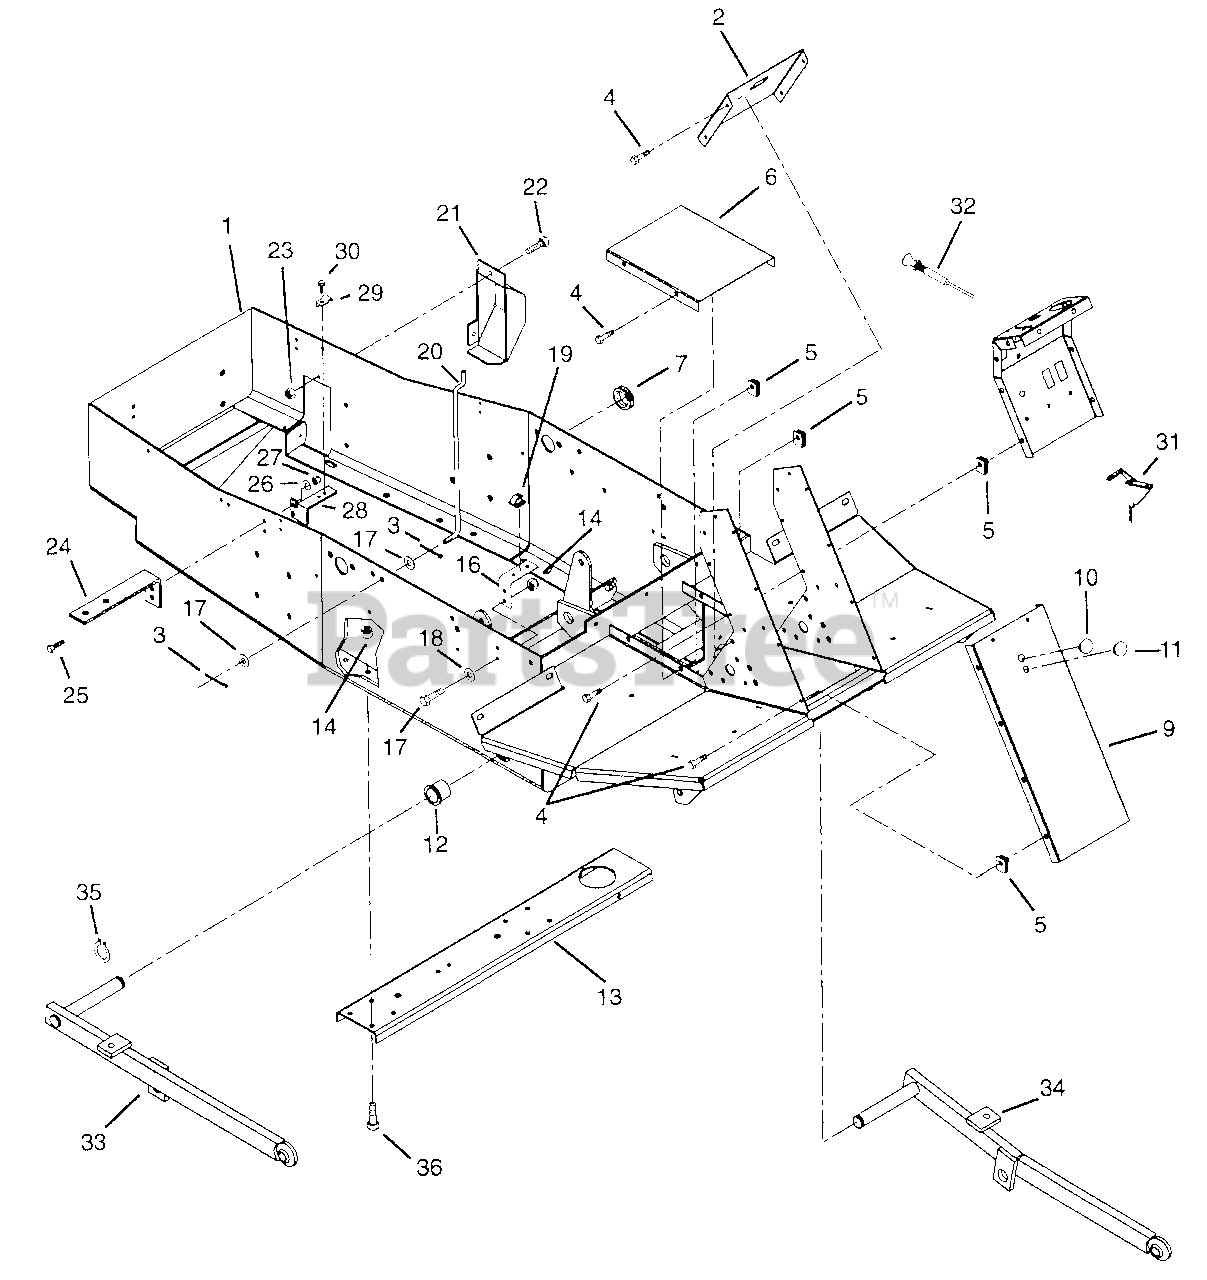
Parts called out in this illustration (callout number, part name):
1	Weldment, PM-350 Frame
2	Panel, Brake Lock
3	Pin-Cotter .09 x .75
4	Screw-Machine .25-20
5	Nut-Retainer .25-20 x .56
6	Panel, Access
7	Grommet, 1.25
8	Panel, Instrument
9	Panel, Front
10	Hole Plug
11	Plug, Hole
12	Bushing, Flange Nylon 1.25 x 1.50 x 1.50
13	Grommet, 1.25
14	Nut-Locking-Nylon .375-16 Grade 2
15	Bolt-Hex .380-16 x .875
16	Bracket,Oil Filter Mount
17	Bolt-Hex .38-16 x 1.00 Grade 5
18	Washer-Flat-Steel .406 x .812 x .065
19	Lever,Choke Control 8 HP
20	Rod,Stay
21	Cover, PTO Pulley
22	Bolt-Hex .25-20 x 1.00 Grade 5
23	Nut-Locking-Nylon .250-20 with Insert Grade 2
24	Bracket, Air Filter Mount (003,300)
25	Bolt-Hex .31-18 x .75 Grade 5 (003,300)
26	Washer-Flat-Steel .344 x .688 x .065 (003,300)
27	Nut-Locking-Nylon .312-18 (003,300)
28	Throttle Cable Bracket (003,300)
29	Clip, Diesel Throttle Cable (003,300)
30	Screw-Machine 10-24 x .62 (003,300)
31	Throttle Cable (003,300)
32	Choke Cable (004)
33	Weldment, Lift Arm Right Hand
34	Weldment, Lift Arm Left Hand
35	Ring-Retaining-External 1.15- x .093
36	Bolt-Hex .38-16 x .875
